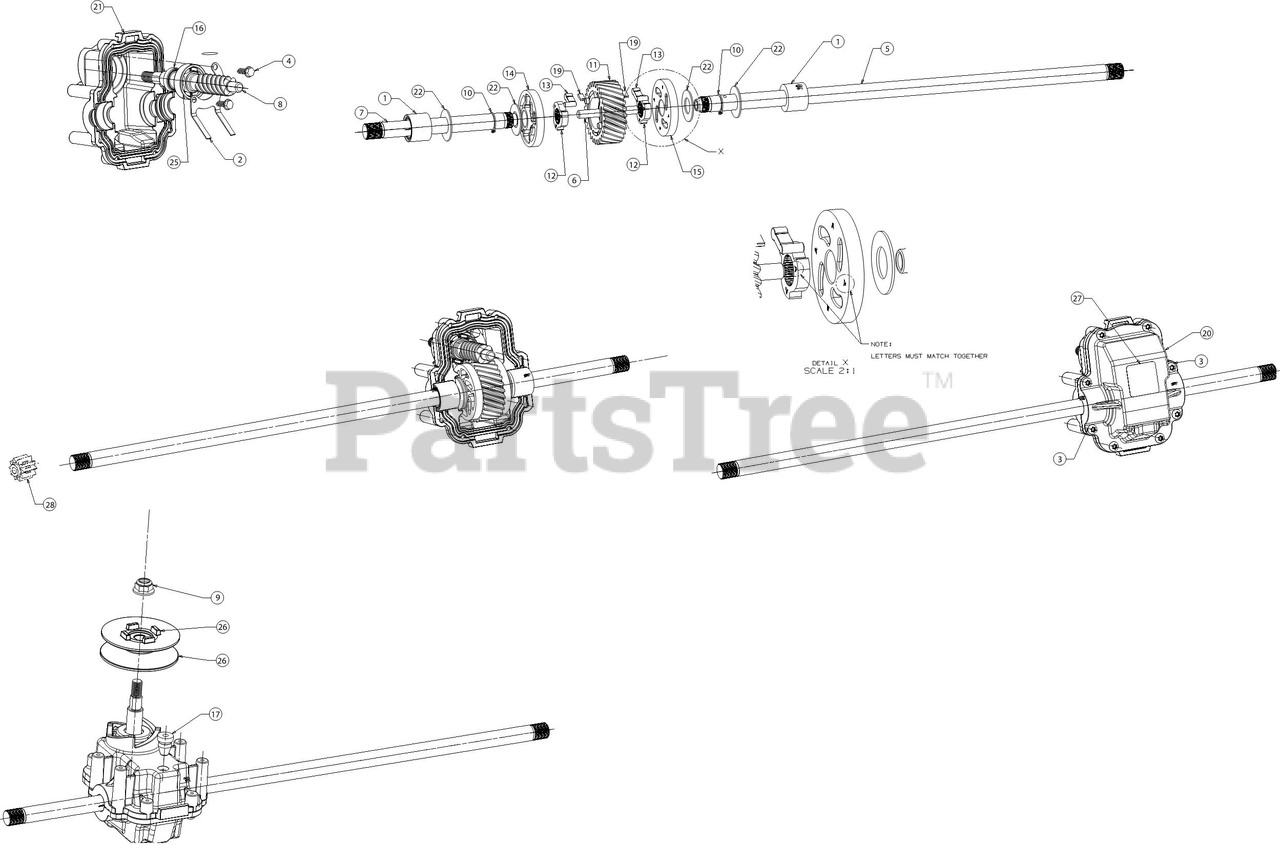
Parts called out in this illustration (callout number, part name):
1	OIL SEAL
3	SCREW .159 x .610
4	SCREW .159 x .43
9	FLANGE LOCK NUT 5/16-18
10	SNAP RING FOR .500
16	OIL SEAL
22	FLAT WASHER .508X1.000X.040
25	BALL BEARING
26	HALF PULLEY 2.5 OD
27	TRANSMISSION COVER
28	SPUR GEAR 9T
